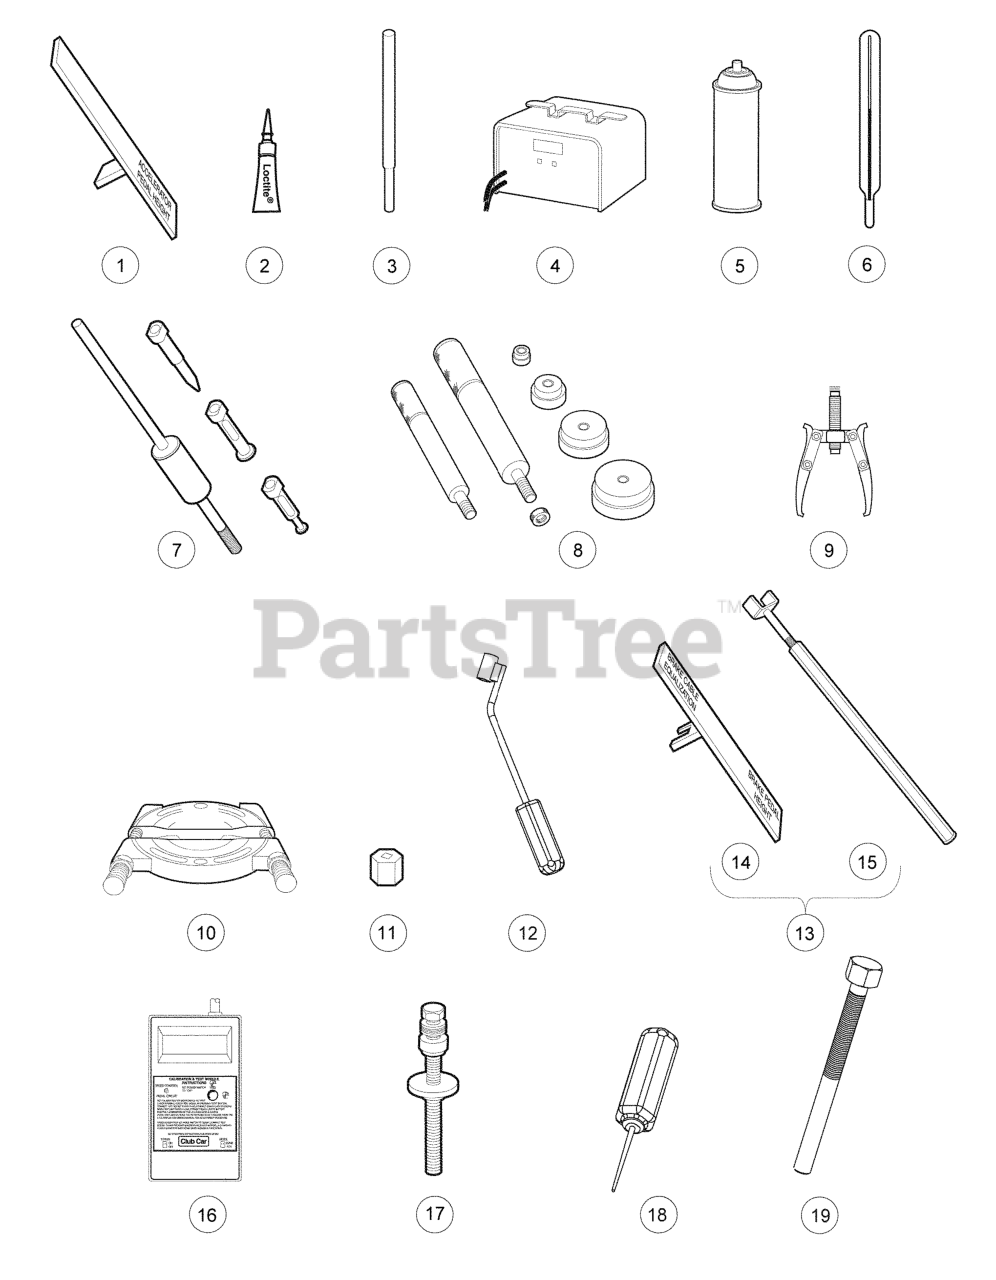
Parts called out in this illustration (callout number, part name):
1	TOOL, ACCEL. PEDAL ADJUSTMENT
2	GUIDE RING ADHESIVE 3 GRAMS
4	BATTERY DISCHARGE UNIT 36/48V
5	BATTERY TERMINAL PROTECT SPRAY
6	BATTERY THERMOMETER
7	BEAR & OIL SEAL REMOVER ASM
8	BEARING DRIVER SET
9	BEARING PULLER
10	BEARING PULLER WEDGE ATTACH.
11	BRAKE ADJUSMENT SOCKET TOOL
12	BRAKE CABLE RELEASE TOOL
13	Brake Pedal Adjustment Tool Kit
14	Brake Pedal Adjustment Tool
15	Brake Pedal Tension Tool
16	CALIBRATION & TEST MODULE
17	CAM INSTALLATION TOOL
18	CHARGER BEZEL TOOL
19	TOOL, REMOVAL, CLUTCH, GAS/DSL
20	C.C. CLUTCH TOOL KIT
21	TOOL, CLUTCH ALIGNMENT
22	TOOL, CLUTCH PULLER
23	CLUTCH DRIVE HUB PULLER
24	DRIVEN CLUTCH CAM PULLER
25	DRIVEN CLUTCH PULLER PLUG
26	DRIVE CLUTCH HOLDER TOOL ASM.
27	PRESS WELDMENT
28	TOOL-STATIONARY PRIMARY
29	TOOL-SPRING COMPRESSION BASE
30	TOOL-SPRING COMPRESSION COLAR
31	TOOL-SPRING COMPRESSION COLAR
32	TOOL-SPIDER PRIMARY
33	COMMUNICATION DISPLAY MODULE
34	COMPRESSION GUAGE AND ADAPTER
35	CONTINUITY TESTER
36	CUTTER, VALVE SEAT, #122
37	CUTTER, VALVE SEAT, #115
38	ADAPTER, T-WRENCH
39	ADAPTER, T-WRENCH
40	Cutter, Valve Seat, 60 Degree
41	PILOT, 6.6 MM
42	PILOT, 6.62 MM
43	PILOT, 6.65 MM
44	LUBRICANT 11OZ CAN SPRAY
45	FLYWHEEL PULLER KIT
46	GAUGE, CARB FLOAT LEVEL
48	INSERT TOOL, GOVERNOR SHAFT
49	ADJUSTER, HYDRAULIC BRAKE
50	HYDROMETER
51	INERNAL RETAINING RING PLIERS
52	KIT, IQDM, USER, SERIES II
53	KIT, IQDM, OEM, SERIES II
54	ADAPTER, 1307 CABLE
55	CABLE, IQDM, SERIES II
56	CABLE, IQDM
57	SEALANT
58	LUBRICANT, MOLY-TEFLON,4 OZ TU
59	TOUCH UP PAINT BEIGE
59	TOUCH UP PAINT, BLACK
59	TOUCH UP PAINT, BURGUNDY
59	TOUCH UP PAINT, CLASSIC BLUE
59	TOUCH UP PAINT, DARK GRAY
59	TOUCH UP PAINT, DARK GREEN
59	TOUCH UP PAINT, GRAY
59	TOUCH UP PAINT, RED
59	TOUCH UP PAINT, ROYAL BLUE
59	TOUCH UP PAINT, WHITE
60	PAINT, GRAY - SPRAY
61	PAINT PEN, UNDERBODY, BLACK
62	KIT, PISTON RING COMPRESSOR
63	PISTON RING PLIER
64	SPECIAL-USE PULLER SET
65	EXTERNAL SNAP RING PLIERS
66	INTERNAL SNAP RING PLIER 9O
67	SAFETY FIRST CARD
68	SEAL PULLER
69	WRENCH, SPANNER
70	Steering Column Bearing Press Tool
71	TOOL-STEERING RETAINING RING
72	PULLER, STEERING WHEEL
73	TACHOMETER GAS/DIESEL
74	TACHOMETER DIESEL ADAPTOR
75	TRANS-AXLE, AXLE SEAL TOOL
76	Transaxle Pinion Seal Tool
77	Transmission Tool Kit
82	VALVE CLEAR ADJ SCREW HOLDER
83	DRIVER, VALVE GUIDE, 6.6. MM
84	VALVE GUIDE REAMER
85	REAMER-VALVE GUIDE
86	VALVE SEAT CUTTER GUIDE
87	VALVE SEAT CUTTER "T" WRENCH
88	VALVE SEAT CUTTER 45 DEG 32 MM
89	CUTTER INTAKE VALVE ST 45/30
90	VALVE SPRING CMPR & ADAPTER
91	METER, WAVETEK VOLT-OHM
92	S/G TENSIONING TOOL
